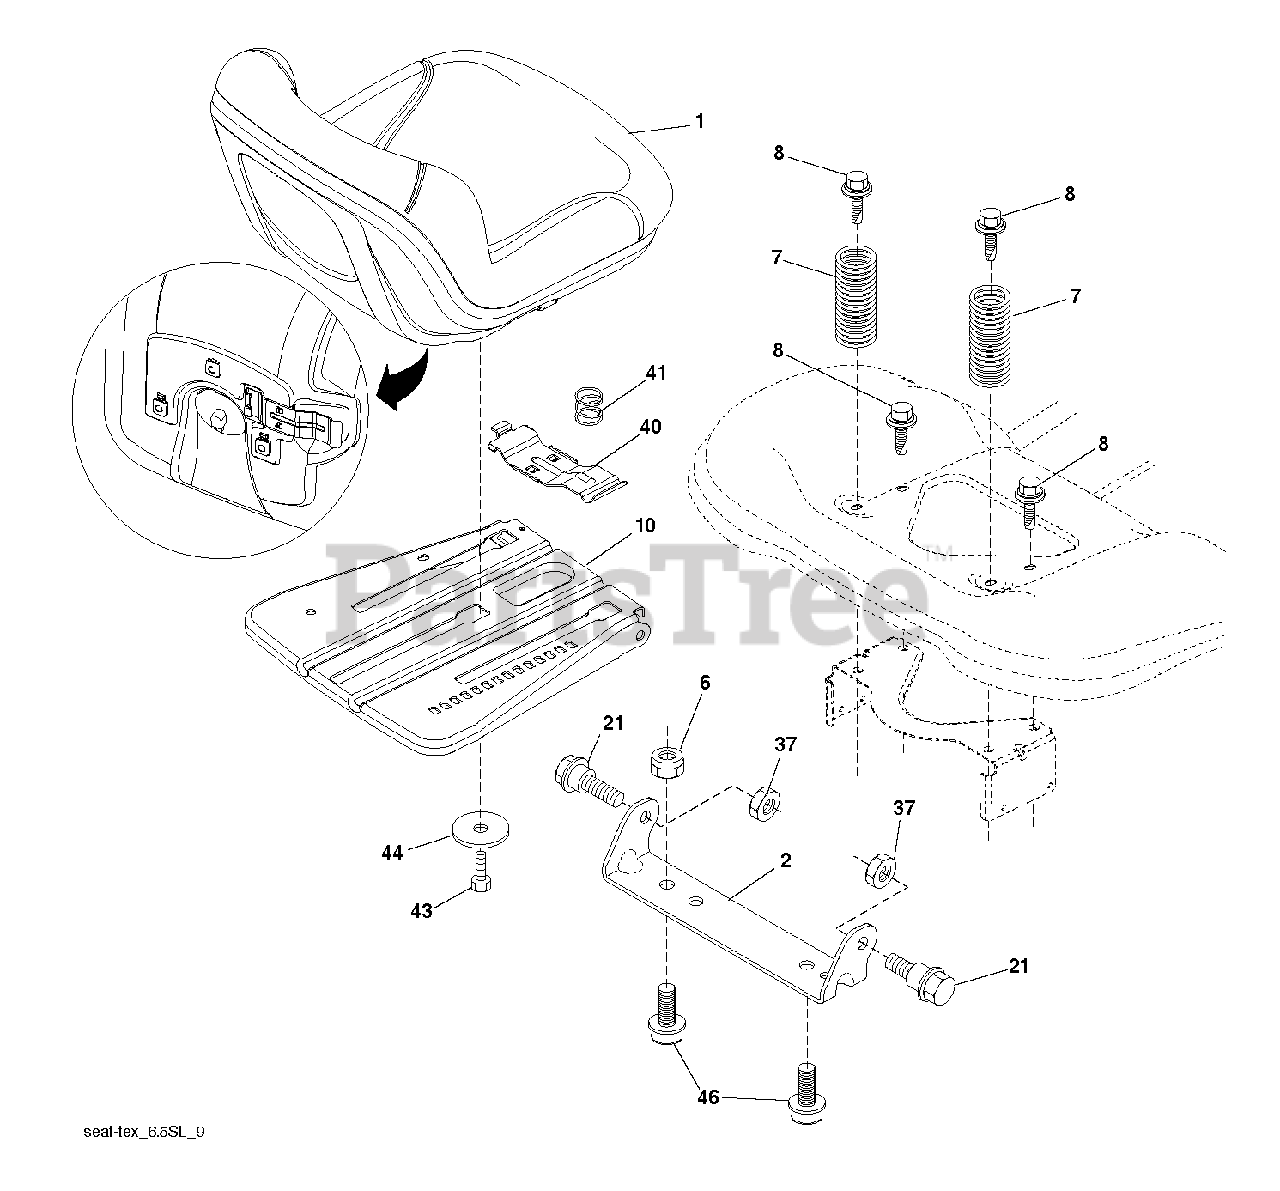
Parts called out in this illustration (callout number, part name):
1	SEAT.TH110.HUSQ.TEX.GREY
2	BRKT.PIVOT.FENDER
3	STRAP
6	NUT
7	SPRING.COMPRESSION.SEAT.BLACK
8	BOLT, 5/16-18 X 1 3/4
10	PAN.ASM.SEAT.3PT
21	BOLT.5/16-18X5/8.SHOULDER
37	NUT.71038.31-18.HEX.NYLOCK
40	HANDLE.SLIDE.SEAT.TEX.BLACK
41	SPRING.LATCH.SEAT.TEX
44	WASHER 13/32 X 2-3/8 X 12GA
46	BOLT.3/8-16X1;1.25OD.WSHR.SEMS
